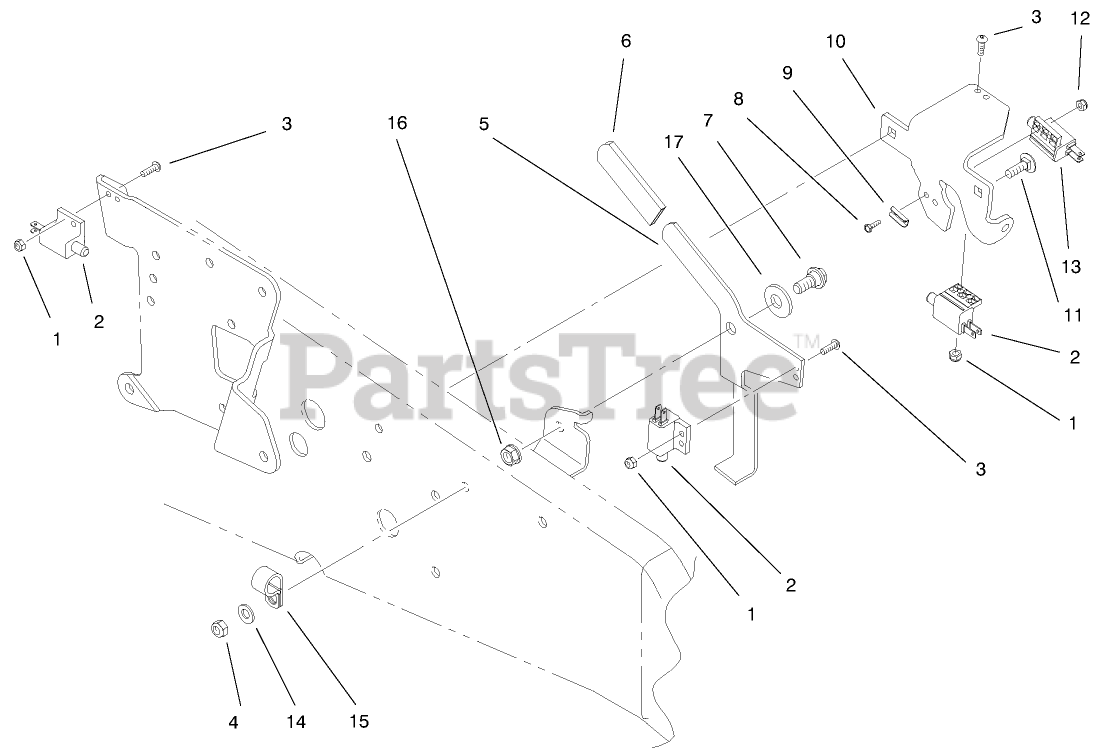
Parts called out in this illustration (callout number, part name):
1	NUT-LOCK, NI
3	SCREW-HSH
4	NUT-LOCK, NI
5	LATCH-BRAKE, PARKING
7	BOLT-SHOULDER
8	SCREW-SHH
9	RETAINER-SCREW
10	BRACKET-SWITCH
11	SCREW-CARR
12	NUT-LOCK
13	SWITCH-POLE, SINGLE
14	WASHER-PLAIN
15	CLAMP - R
16	NUT-HEX
17	WASHER
